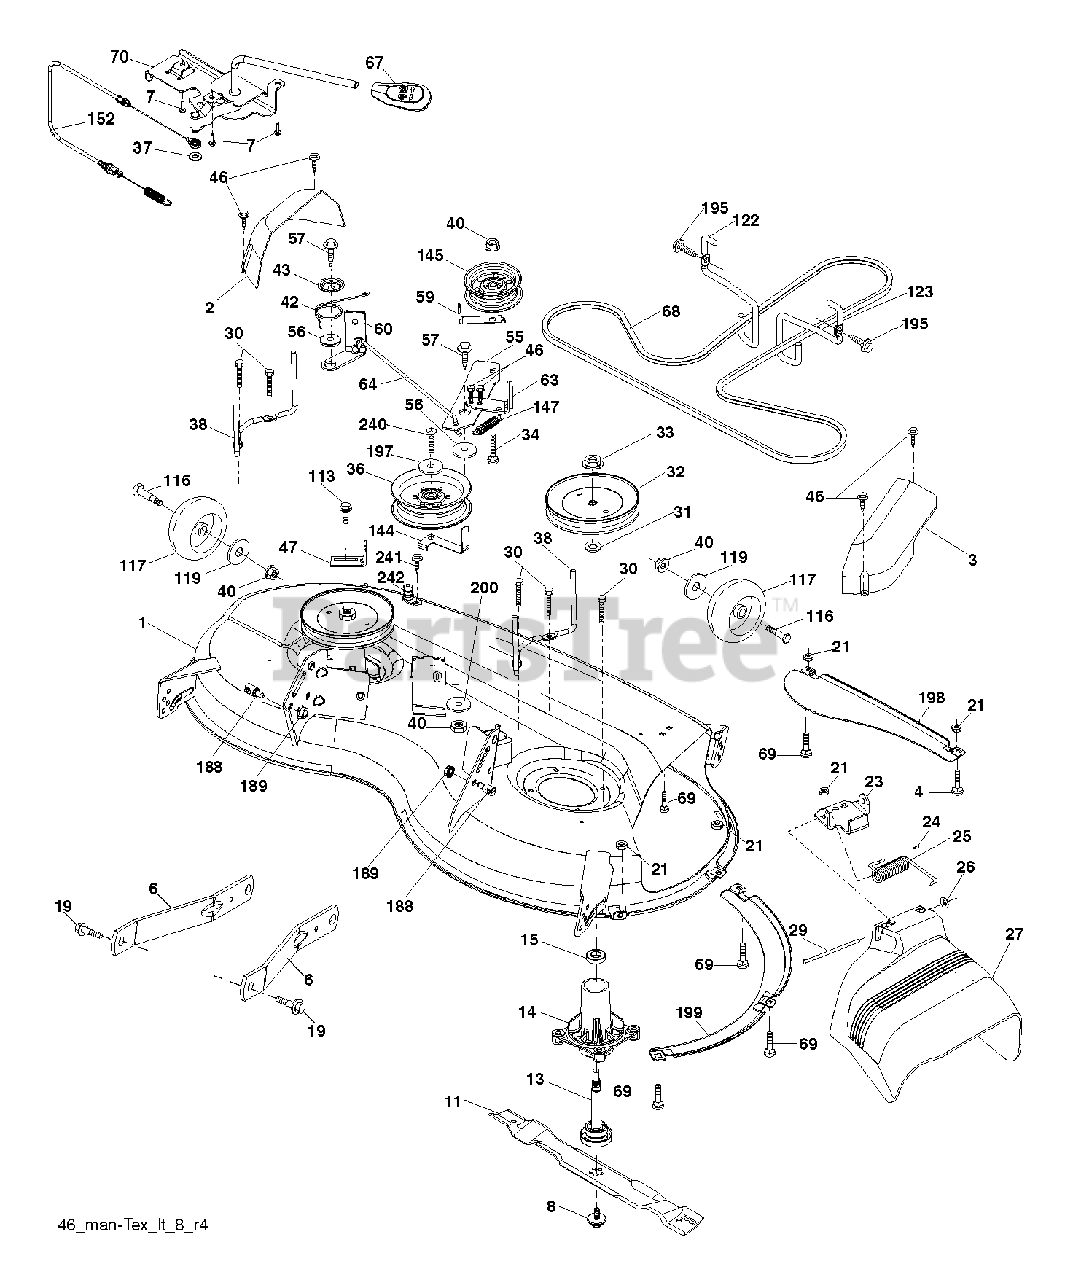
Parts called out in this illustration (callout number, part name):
2	COVER.MANDREL.LH.46"
3	COVER MANDREL RH
4	BOLT
6	ARM.SUSPENSION.MOWER.R
7	SCREW.#10 X 0.750.BOS THREAD
8	BOLT.WASHER.ASM.7/16-2
11	BLADE 46" HI LIFT
13	SHAFT.ASM.MDRL.N/GREASE.38
14	HOUSING MANDREL
19	BOLT.SHOULDER
21	LOCKNUT
24	CAP-SLEEVE LT
25	SPRING.TORSION.DEFLECT
26	NUT PUSH M
27	SHIELD.DEFLECTOR.MOWER.46"BLAC
29	ROD.HINGE
30	SCREW, WASHER HEAD
31	WASHER.SPACER.MANDREL
32	PULLEY.MANDREL.5.438.PD
33	NUT.FLANGE.LOCK.TOP
34	BOLT.3/8-16X1.50
36	PULLEY.IDLER.2006
38	KEEPER.BELT.MANDREL.PULLEY
40	NUT LOCK FLG 3/8-16 UNC
42	SRPING.TORSION.RETAINE
43	SPRING.TORSION.BRAKE
46	SCREW.1/4-20X5/8
47	BELT.DRIVE.DECK
55	IDLER.ARM
56	SPACER.RETAINER
57	SCREW 3/8-16X1
59	GUARD, BELT
60	ARM BRAKE MOWER RH 38"
63	ARM BRAKE MOWER
64	LINKAGE BRAKE
67	HANDLE.CLUTCH.CABLE.LT
68	V BELT
69	BOLT
70	CLUTCH.ASM.MANUAL.YT.PREDATORQ
116	BOLT.SHOULDER.3/8-16X3-5/8
117	WHEEL. GUAGE RALLY
122	KEEPER BELT ENGINE LH
123	KEEPER BELT RH
144	KEEPER.BELT.MOWER
145	PULLEY.IDLER.48"PRIMARY
147	SPRING RETURN
152	CABLE.CLUTCH.MANUAL.
188	STUD.FASTNER.W/ANTI-ROTATE
189	NUT LOCK HEX FLANGE 5/16-18
195	SCREW, 3/8-16X3/4
197	WASHER
198	BAFFLE CENTER FRONT
199	BAFFLE FRONT RH
200	WASHER.13/32 X 1 X 1/2.11GUARD
240	BOLT-HEX EAK
242	PORT.WASHOUT
